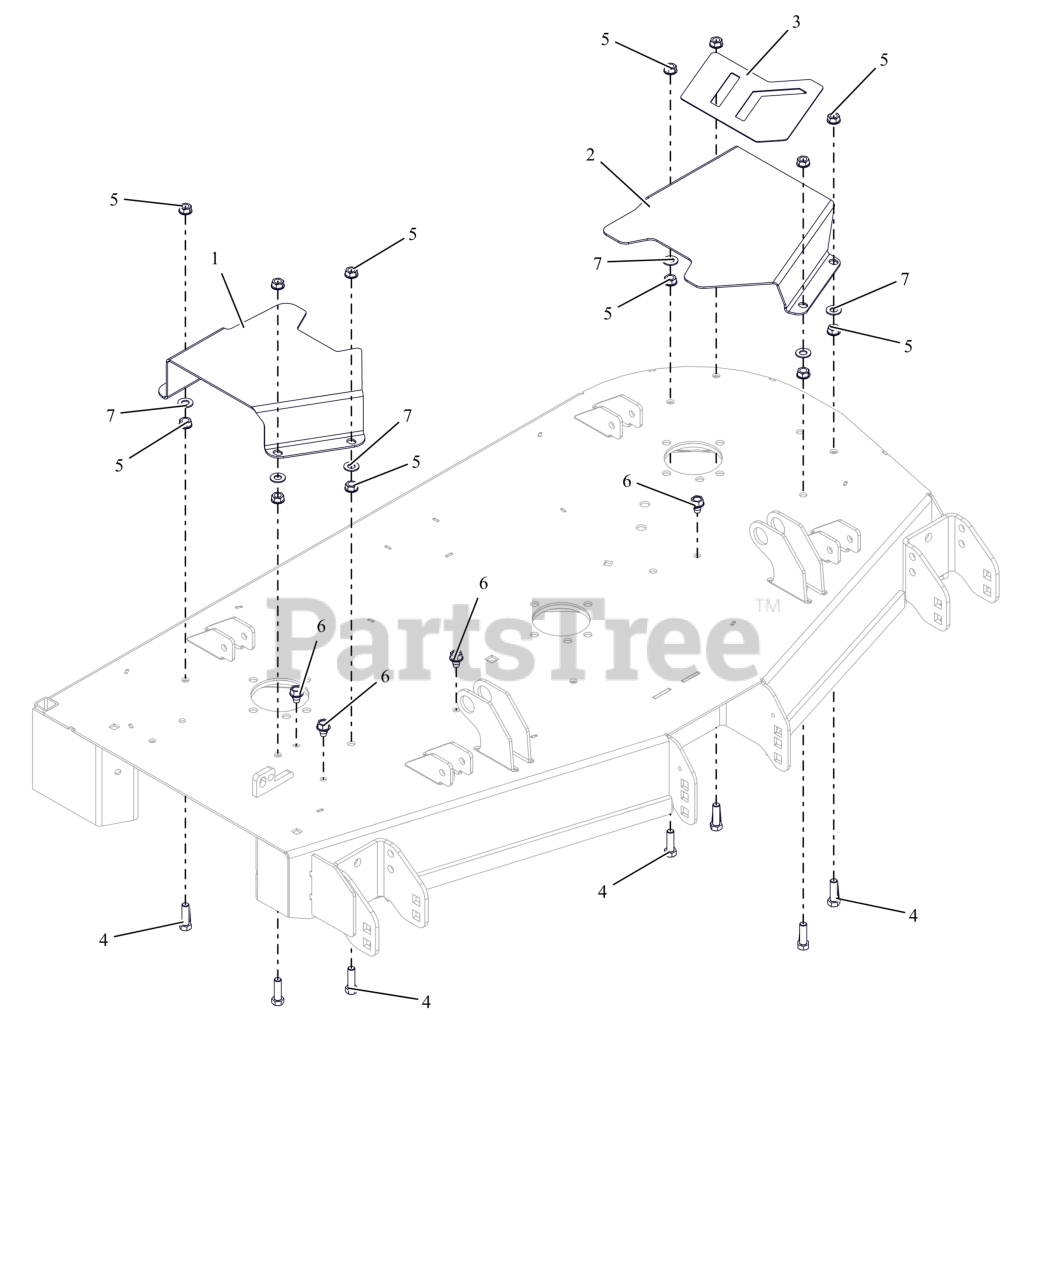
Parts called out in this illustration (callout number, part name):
1	COVER, BELT 48" RIGHT
2	COVER, BELT 48" LEFT
3	GRIP, TAPE 48 BELT COVER
4	BLT, HEX .38-16X1.25 G5 ZCC
5	NUT, SPNLK-FLG .38-16 G5 ZCC
6	SCR,TAP .375-16X.50 HWH TR ZCC
7	WSHR,FLT .406X.812X.065 ZCC
